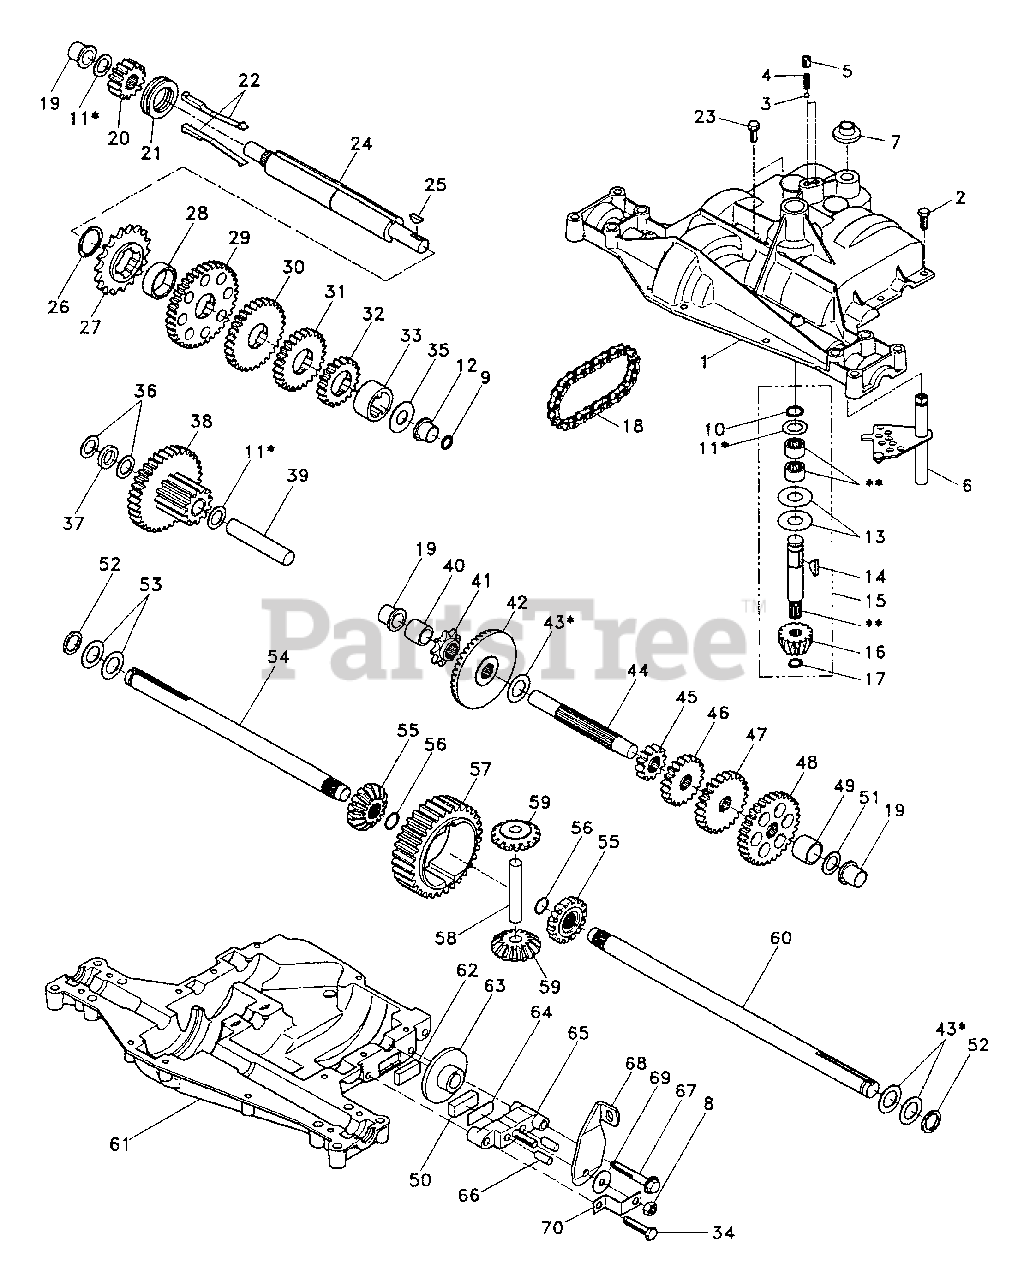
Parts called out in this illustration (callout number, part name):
1	Housing, Upper
2	Screw, Self-Tapping, Large 1/4-20 x .734
3	Ball, Detent
4	Spring, Detent
5	Screw, Set
6	Kit, Shifter Assembly
7	Boot, Shifter
8	Locknut 5/16-24
9	Square Ring
10	Ring, Retaining
11	Assembly, Kit, Shim .625 Shaft
12	Bearing, Flange
13	Washer, Plain .632 x 1.38 x .046
14	Key, Woodruff, #9
15	Assembly, Kit, Input Shaft
16	Pinion, Bevel, 14 Teeth
17	Ring, Retaining
18	Chain, 24 Pitches
19	Bearing, Flange
20	Gear, Spur, 14 Teeth
21	Collar, Clutch
22	Assembly, Kit, Clutch Keys
23	Screw, Self-Tapping, with Sealer
24	Shaft, Intermediate
25	Key, Woodruff, #61
26	Ring, Retaining
27	Sprocket, 18 Teeth
28	Spacer
29	Gear, Spur, 37 Teeth
30	Gear, Spur, 30 Teeth
31	Gear, Spur, 25 Teeth
32	Gear, Spur, 19 Teeth
33	Spacer 1.133 x 1.50 x .750
34	Screw, Self-Tapping 5/16-18 x 1.40
35	Washer, Plain .640 x 1.37 x .061
36	Washer, Plain .632 x 1.00 x .026
37	Spacer .630 x 1.00 x .169
38	Assembly, Gear, Combination of 12 Teeth and 35 Teeth
39	Shaft, Idler
40	Spacer .635 x .875 x .755
41	Sprocket 9 Teeth
42	Gear, Bevel, 42 Teeth
43	Assembly, Kit, Shim, .750 Shaft
44	Shaft, Drive
45	Gear, Spur, 12 Teeth
46	Gear, Spur, 20 Teeth
47	Gear, Spur, 25 Teeth
48	Gear, Spur, 31 Teeth
49	Spacer .781 x 1.00 x .750
50	Puck, Friction
51	Washer, Plain .632 x 1.00 x .060
52	Washer, Neoprene
53	Washer, Plain .758 x 1.25 x .031
54	Axle, L.H.
55	Gear, Miter, 15 Teeth
56	Ring, Retaining
57	Gear, Spur, 32 Teeth
58	Shaft, Cross
59	Gear, Miter, 15 Teeth
60	Axle, R.H.
61	Housing, Lower
62	Puck, Friction
63	Disc, Brake
65	Jaw, Brake
66	Pin, Dowel
67	Screw, Self-Tapping 5/16-18 x 2.25
68	Lever, Actuating
69	Washer, Plain .321 x 1.00 x .055
70	Bracket, Anti-Rotation
